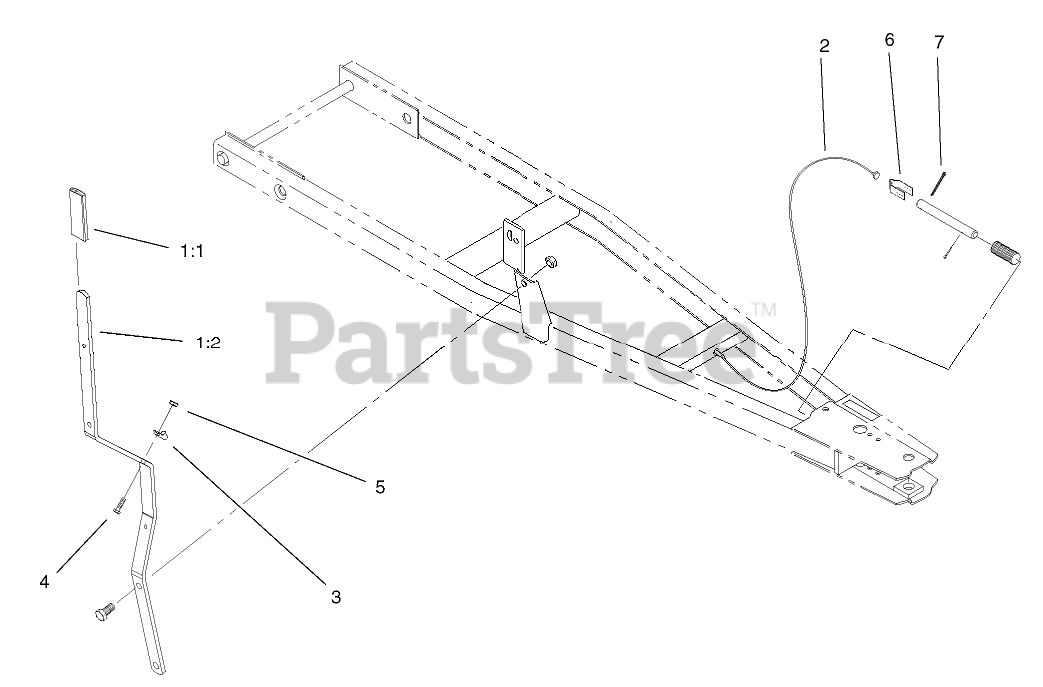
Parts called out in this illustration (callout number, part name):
1:1	GRIP
1:2	LEVER-INDEX
2	CABLE-INDEXING, DOZER
3	R-CLAMP
4	SCREW-HH
5	NUT-LOCK
6	BRACKET - CABLE END
7	PIN-COTTER
